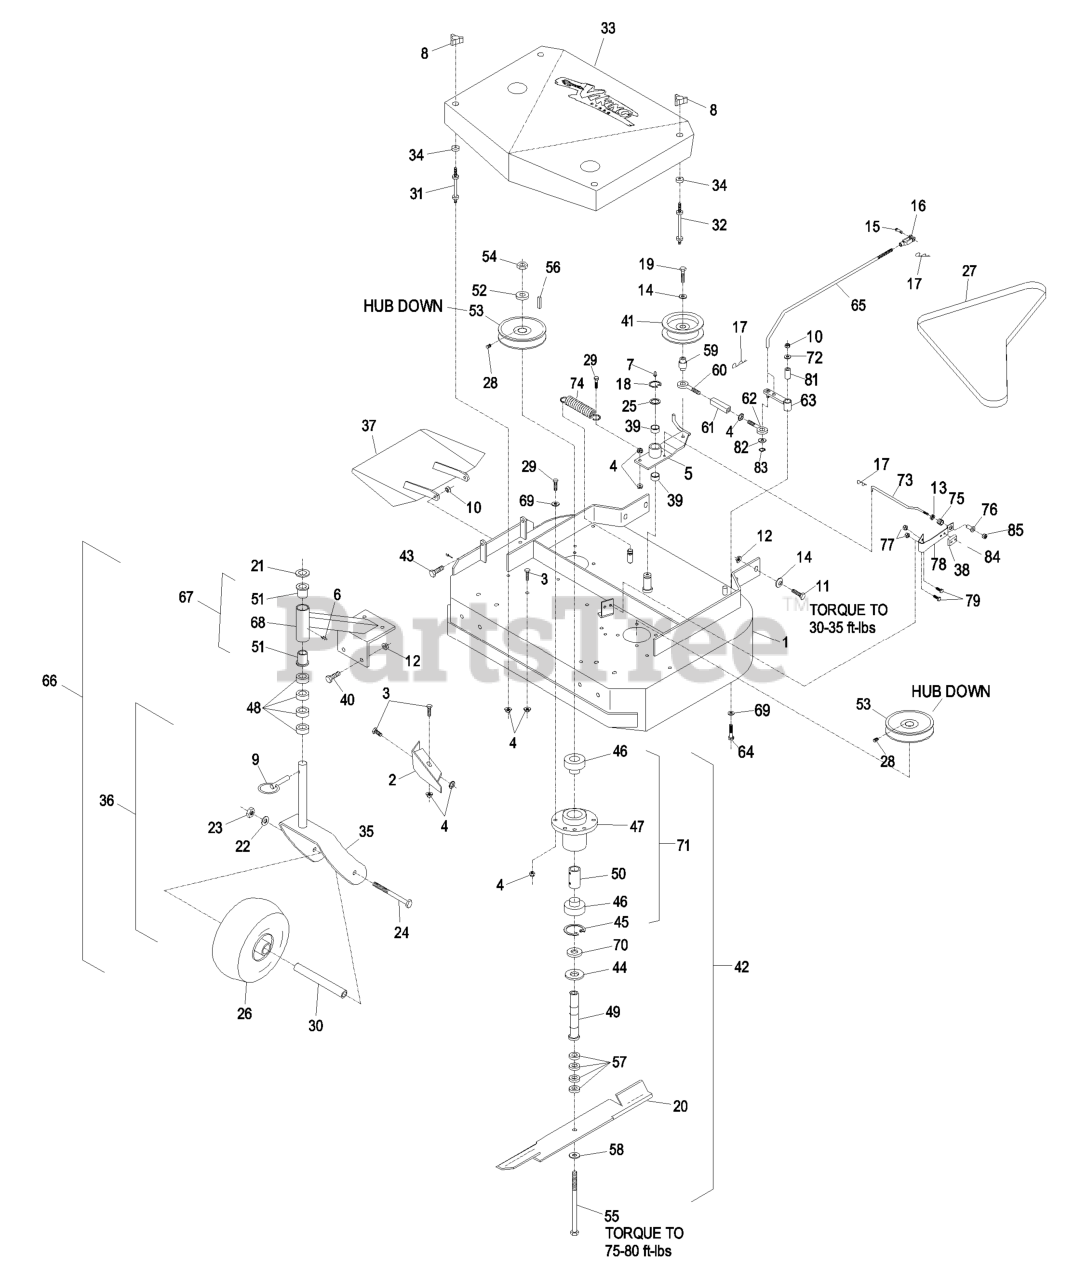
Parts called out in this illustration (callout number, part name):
2	BAFFLE-DOGLEG
8	KNOB-3 PRONG
13	RING-PUSH ON
15	PIN-CLEVIS
16	YOKE-ADJUSTABLE
17	PIN-COTTER
21	WASHER-FLAT
25	WASHER-SPINDLE
27	BELT,BLADE VIKING HYD 36
28	SCREW-SET
31	STUD-SHIELD, BELT (SHORT)
32	STUD-SHIELD, BELT (LONG)
37	WLD,CHUTE 36 RIGID
38	PAD-BRAKE
39	SLEEVE-BEARING
42	HOUSING,CUTTER COMPLETE(S
44	GUARD-BEARING, BOTTOM
46	BEARING
48	SPACER-CASTER
49	TUBE-SPINDLE, SHORT
50	SPACER-BEARING
51	BEARING-FLANGED
52	WASHER-RETAINER, SHEAVE
53	SHEAVE
55	SCREW-CAP, HH
58	WASHER-SPRING
59	BUSHING-ENGAGEMENT
60	EYEBOLT-THREAD, LH
61	BODY-TURNBUCKLE
62	EYEBOLT-THREAD, RH
63	ARM-ASSIST, 32/36
65	ARM-ASSIST, LINKAGE
66	CASTER/MOUNT ASM
67	SUPPORT ASM
69	WASHER-SPRING
70	SPACER-PULLEY/BEARING
73	ROD-BRAKE
74	SPRING-EXTENSION
75	SPRING-COMPRESSION
76	SPACER-FLANGED
78	PAD AND SPRING ASM
81	TUBE-PIVOT
